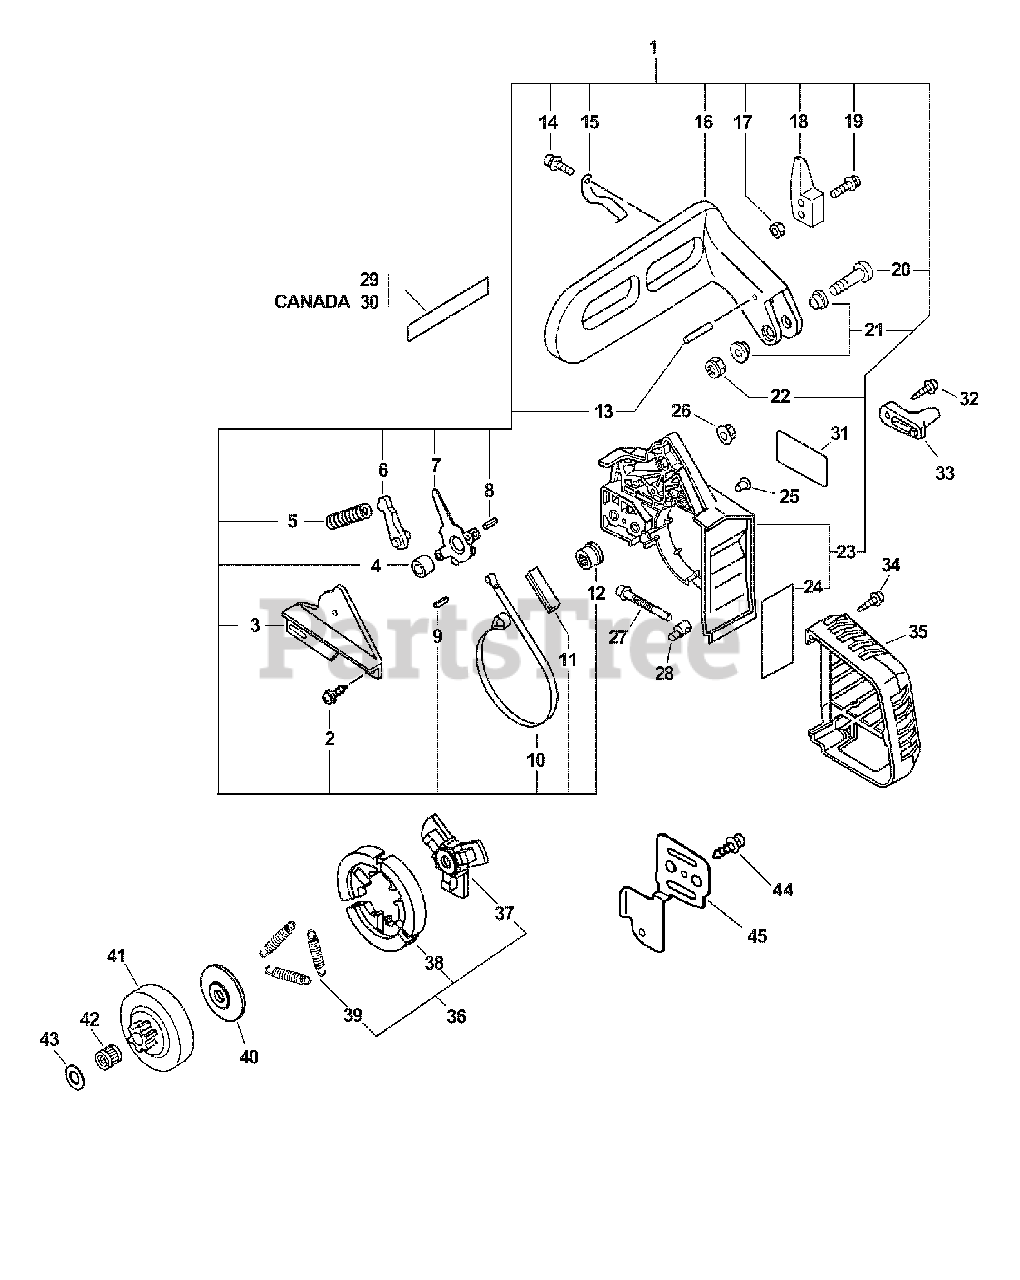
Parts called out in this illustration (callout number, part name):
1	CHAIN BRAKE ASSY
2	SCREW - 4X12 -- TAPPING
3	COVER, BRAKE - GRAY
4	SPACER - 8
5	SPRING, BRAKE
6	STOPPER, BRAKE
7	LEVER, BRAKE
8	PIN - SPRING -- 4X8
9	PIN - SPRING -- 2.5X12
10	BAND, BRAKE
12	ADJUSTER, BRAKE BAND
13	ROLLER - 4X23.8
14	SCREW - 4X10
15	SPRING, RETURN
16	LEVER, BRAKE - ORANGE
18	WEIGHT, BRAKE
19	SCREW - 4X22
20	SCREW - 5X32
22	LOCKNUT - 5
23	GUARD, SPROCKET - GRAY
24	DEFLECTOR, HEAT
26	NUT - 6 -- FLANGE
27	SCREW, TENSIONER
28	TENSIONER, CHAIN
29	LABEL - BAR & CHAIN
30	LABEL - BAR & CHAIN
31	LABEL - MODEL CS-305
32	SCREW - 5X20 -- TAPPING
33	CATCHER, CHAIN
34	SCREW - 5X20 -- TAPPING
35	COVER, EXHAUST
36	CLUTCH ASSY
37	HUB, CLUTCH
38	CLUTCH SHOE SET
39	SPRING, CLUTCH
40	PLATE, CLUTCH
41	DRUM, CLUTCH
42	BEARING, NEEDLE
44	SCREW - 4X10
45	PLATE, GUIDE - OUTER
